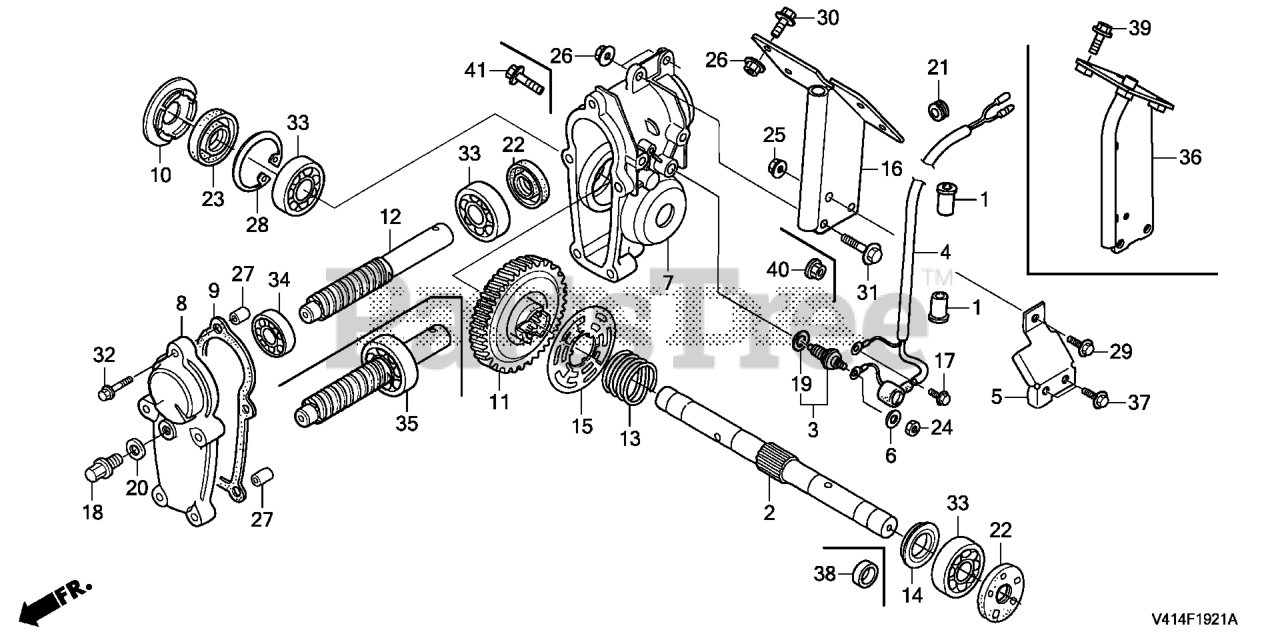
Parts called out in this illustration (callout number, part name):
1	CUSHION, FUEL TANK PIVOT
2	SHAFT, AUGER
3	SWITCH ASSY., LIMIT
4	WIRE, LIMIT SWITCH
5	GUARD, LIMIT SWITCH
6	RUBBER, SEPARATOR
7	CASE, AUGER TRANSMISSION
8	COVER, AUGER TRANSMISSION
9	GASKET, AUGER TRANSMISSION
10	CAP, AUGER CASE
11	GEAR, DRIVEN (55T)
13	SPRING, SLIP SENSOR
14	HOLDER, SHIFTER SPRING
15	PLATE, SLIP SENSOR
17	BOLT, FLANGE (5X10)
18	BOLT, DRAIN PLUG
19	WASHER, NEUTRAL SWITCH
20	WASHER, DRAIN PLUG (10.2MM)
22	OIL SEAL (20X32X7)
23	OIL SEAL (20X42X8)
24	NUT, HEX. (4MM)
25	NUT, FLANGE (6MM)
27	PIN A, DOWEL (8X14)
28	CIRCLIP (INNER) (42MM)
29	BOLT, FLANGE (6X12) Use from Engine SN 2086984.
32	BOLT, FLANGE (6X32)
33	BEARING, RADIAL BALL (6004)
34	BEARING, RADIAL BALL (6202)
35	GEAR, DRIVE (6T)
36	BRACKET, AUGER HOUSING
37	BOLT, FLANGE (6X12) (CT200)
38	COLLAR, AUGER TRANSMISSION (B)
39	BOLT, FLANGE (8X18)
40	NUT, FLANGE (8MM)
41	BOLT, FLANGE (8X25)
